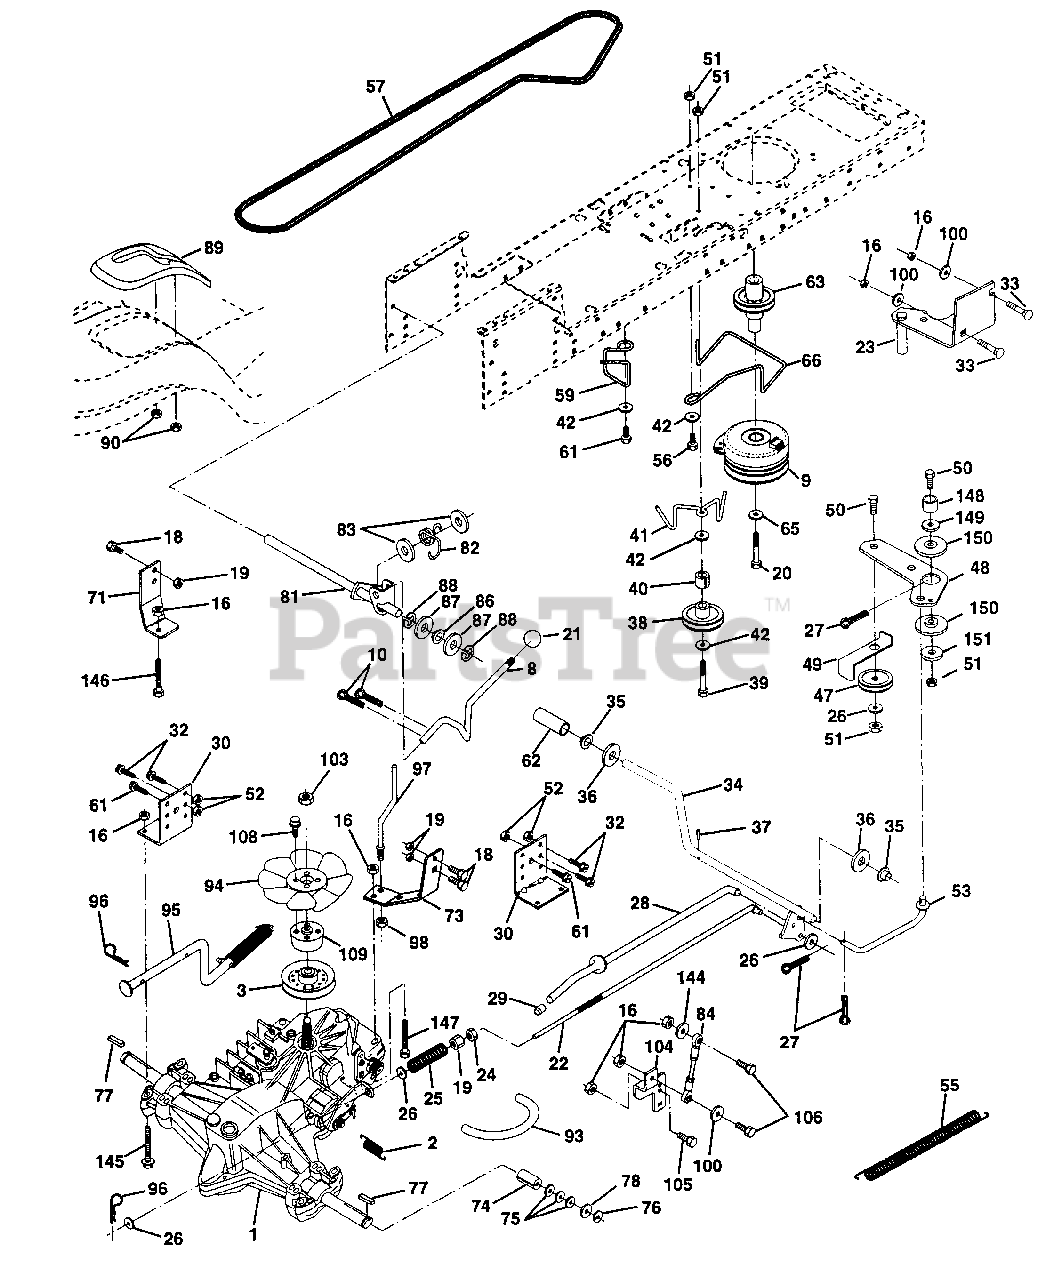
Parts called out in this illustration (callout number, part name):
1	Transaxle
2	Spring, Return, Brake
3	Pulley, Transaxle
8	Rod Shift Fender STLT
9	Clutch, Elect. EVX LT Mag 5217-2
10	Pin Cotter 1/8 x 1 CAD
16	Nut Lock Hex W/Ins. 5/16-18 Unc P
18	Bolt Fin Hex 3/8-16 Unc x 1 Gr. 5
19	Nut Lock Hex W/Wsh 3/8-16 Unc
20	Bolt Hex 7/16-20 x 4-1/4 Ga. 1.38
21	Knob, Duckhead 1/2-13
22	Rod, Brake Hydro
23	Bracket, Asm Clutch Mtg EVX
24	Nut
25	Spring, Brake Rod
26	Washer
27	Pin Cotter 1/8 x 3/4 CAD.
28	Rod, Parking Brake
29	Cap, Parking Brake
30	Bracket, Transaxle
32	Bolt Hex Hd 5/16-18 Unc x 3/4
33	Bolt Rdhd Sqnk 5/16-18 UNC x 3/4
34	Shaft, Foot Pedal
35	Bearing, Nylon
37	Pin, Roll
38	Pulley, Idler, Flat
40	Spacer, Split
41	Keeper, Belt Idler
42	Washer 13/32 x 13/16 x 12 Gauge
47	Pulley, Idler, V-Groove
48	Bellcrank Clutch Grnd Drv Stl
49	Retainer, Belt
50	Bolt
52	Nut Crownlock 5/16-18
53	Link, Clutch
55	Spring, Return, Clutch
56	Bolt Fin Hex 3/8-16 UNC x 1-1/4
57	Y-Belt, Ground Drive
59	Keeper, Center Span
61	Screw Thdrol. 3/8-16 x 3/4 Ty. TT
62	Cover, Pedal
63	Pulley, Clutch Electric EVX
65	Washer
66	Keeper Belt Engine Hydro
71	Strap Torque Lh Hydro
73	Strap Torque Rh Hydro
74	Spacer, Split
75	Washer 25/32 x 1-1/4 x 16 Gauge
77	Key, Square
78	Washer 25/32 x 1-5/8 x 16 Gauge
81	Shaft Asm. Cross Hydro
82	Spring Torsion T/A
83	Washer 17/32 x 3/4 x 16 Ga.
84	Rod, Tie Hydro
86	Bushing Rod Steering 629/632 ID
87	Washer 21/32 x 1-1/4 x 16 Ga.
88	Ring Klip #5304-62
89	Console, Shift
90	Nut, Self-Thd Wsh-hd 1/4 Zinc
93	Line Fuel Hydro 4"
94	Fan, Hydro 7"
95	Control Asm Bypass Hydro
96	Retainer Spring 1" Zinc/Cad
97	Keeper Belt Rh Hydro
98	Nut Keps Hex 3/8-16 Unc
100	Washer 11/32 x 3/4 x 16 Ga.
103	Nut Nylon Insert 1/2-20 Unf.
104	Arm, Control Hydro
105	Screw Cap Hex 5/16 x 18 x 1
106	Bolt Fin Hex 5/16-18 Unc x 1-1/4
108	Screw Hex Wh Hd #10-24 x
109	Adaptor Fan Hydro LT Hyd Alum
144	Washer 11/32 x 5/8 x 16 Ga.
145	Bolt, Hex Flghd 5/16-18 Gr. 5
146	Bolt Hex Flghd 5/16-18 x 2-1/4
147	Bolt Hex Flghd 5/16-18 x 1-1/2
149	Spacer Retainer PM Mower
150	Bushing Nylon Collered
151	Washer 13/32 x 2 x 10 Ga.
